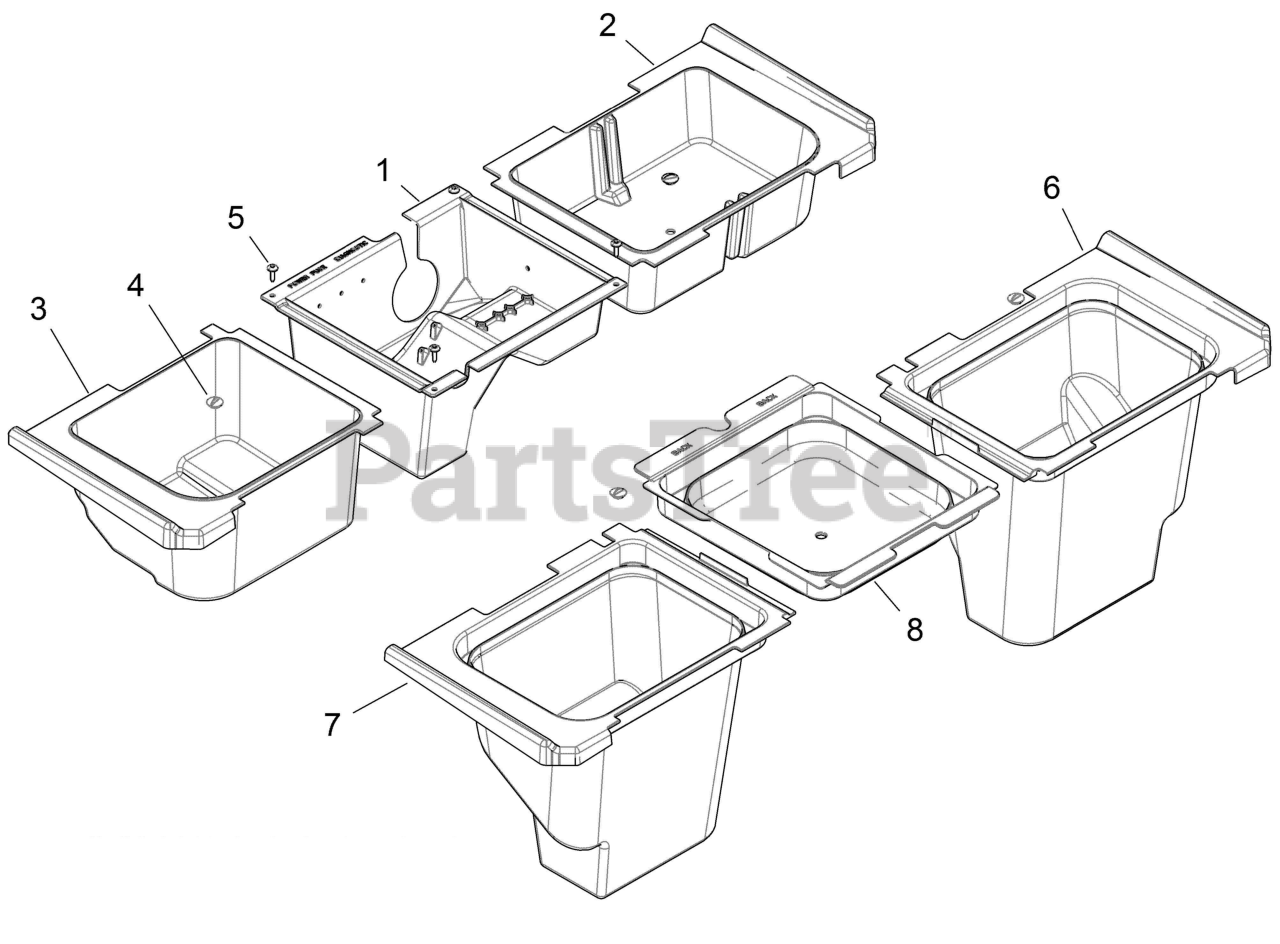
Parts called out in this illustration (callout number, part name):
1	STORAGE BOX,CENTER,BLK
2	STORAGE BOX,LH,BLK
3	STORAGE BOX,RH,BLK
4	PLUG-COMPARTMENT
5	SCR-TXTH-M6X1.0X25 RIE
6	STORAGE BOX,LH,BLK
7	STORAGE BOX,RH,BLK
8	BOX, STORAGE, CENTER, BLACK
